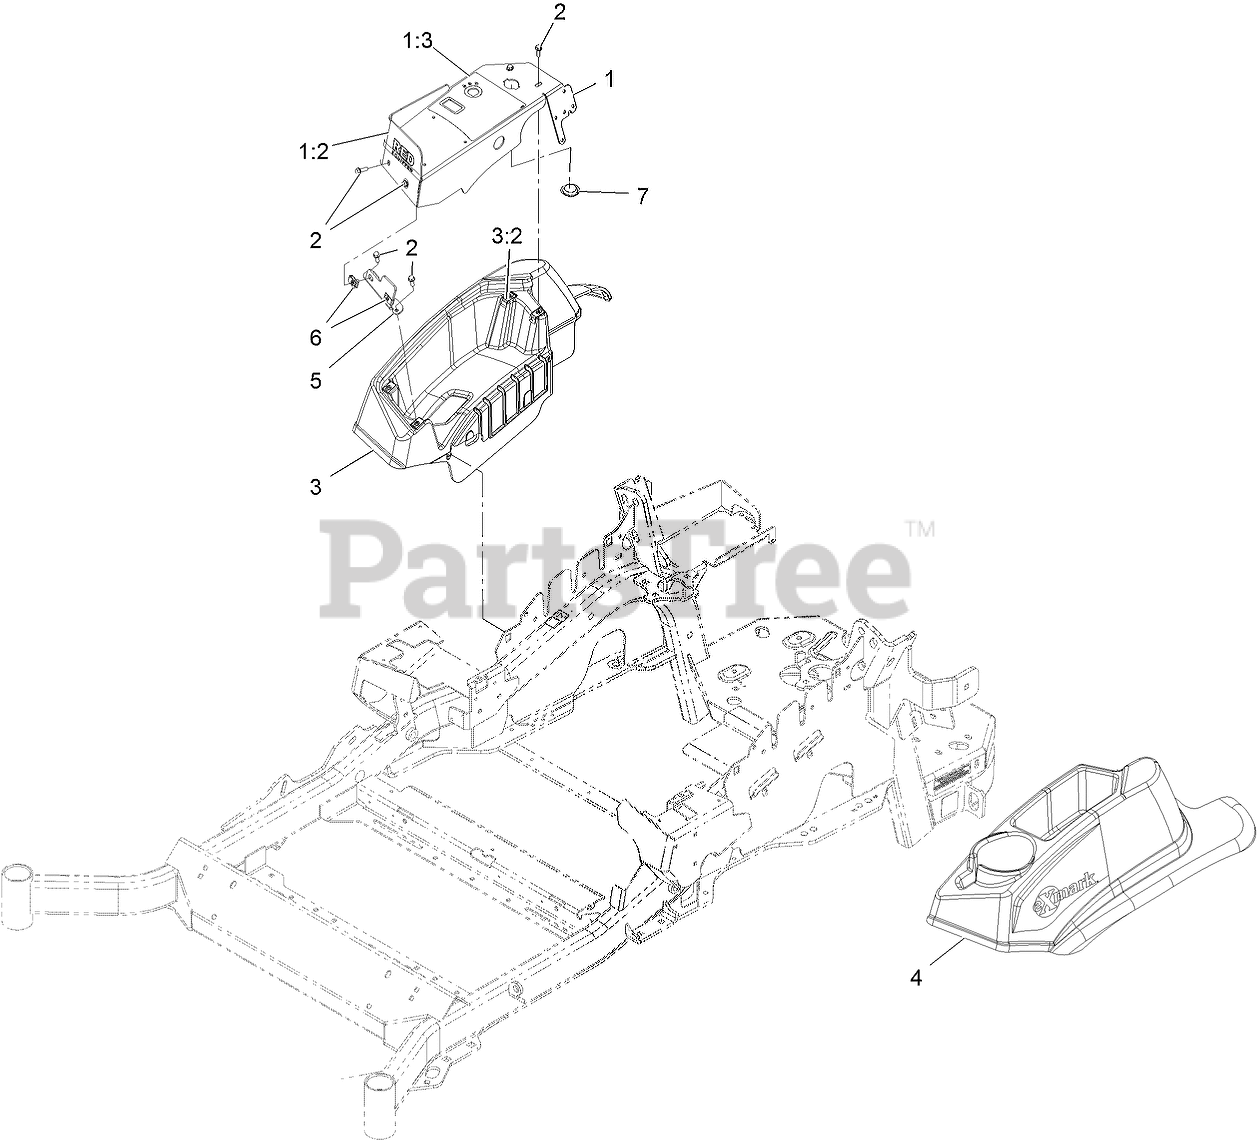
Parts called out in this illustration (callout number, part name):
1	COVER PANEL ASM W/DECALS
1:2	DECAL-CONTROL PANEL RED
1:3	DECAL-CONSOLE
2	SCREW-HWH
3	CONSOLE,RH AS ASM
4	CONSOLE, LH AS
5	BRACKET-CONSOLE
7	PLUG-PLASTIC
